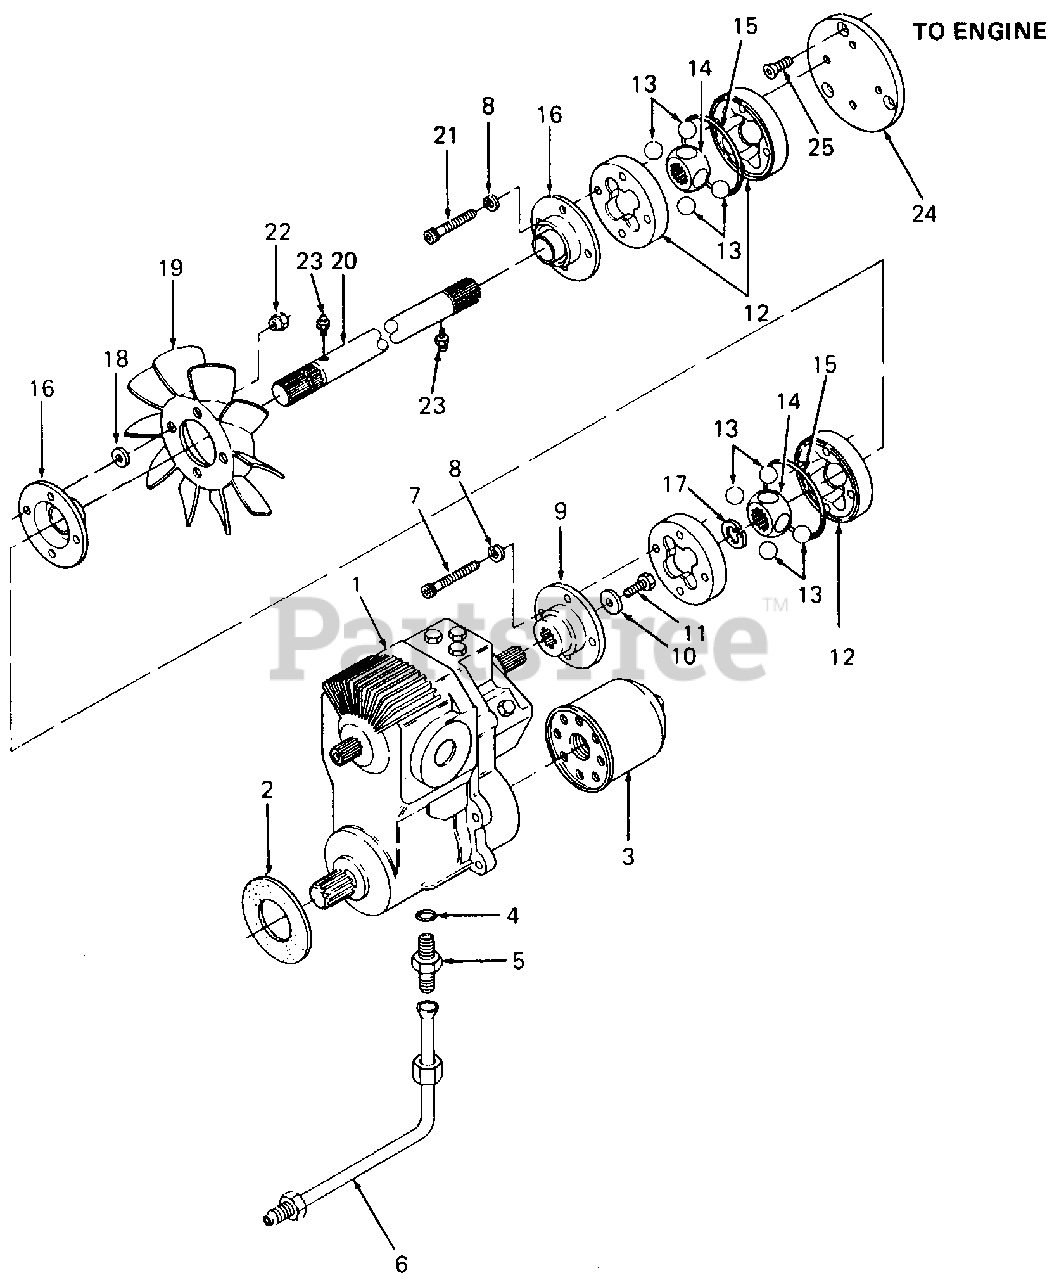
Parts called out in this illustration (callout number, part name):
1	Pump, Hydrostatic
2	Gasket, Front
3	Filter, Oil
4	O-Ring, 5/8 OD Tube
5	Connector, 37 Degree
6	Tube Assy
7	Screw, Socket Hd Cap, 1/4-20 X 2.0 Lg
8	Washer, Lock, 1/4
9	Adapter, Pump
10	Washer, Bell, .265 X .75 X .062 Thk
11	Screw, Hex Patch, 1/4-20 X 1.0 Lg GR5
12	Coupling, Drive w/O-Ring Groove
13	Ball, Steel, 5/8 Dia Chrome
14	Hub, Drive
15	O-Ring, 2.489 X .070
16	Boot, Coupling
17	Ring, Snap
18	Washer, Flat, .25 X .62 X .052 Thk
19	Fan, 10 Blade Hydro
20	Shaft, Drive, 22.88 Lg
21	Screw, Hex Patch, 1/4-20 X 1.62 Lg GR5
22	Nut, Fan, 1/4-20
23	Fitting, Grease
24	Plate, Coupling Adapter
25	Screw, Flat Hd Cntsnk w/Patch, M8 X 16 Lg GR5
